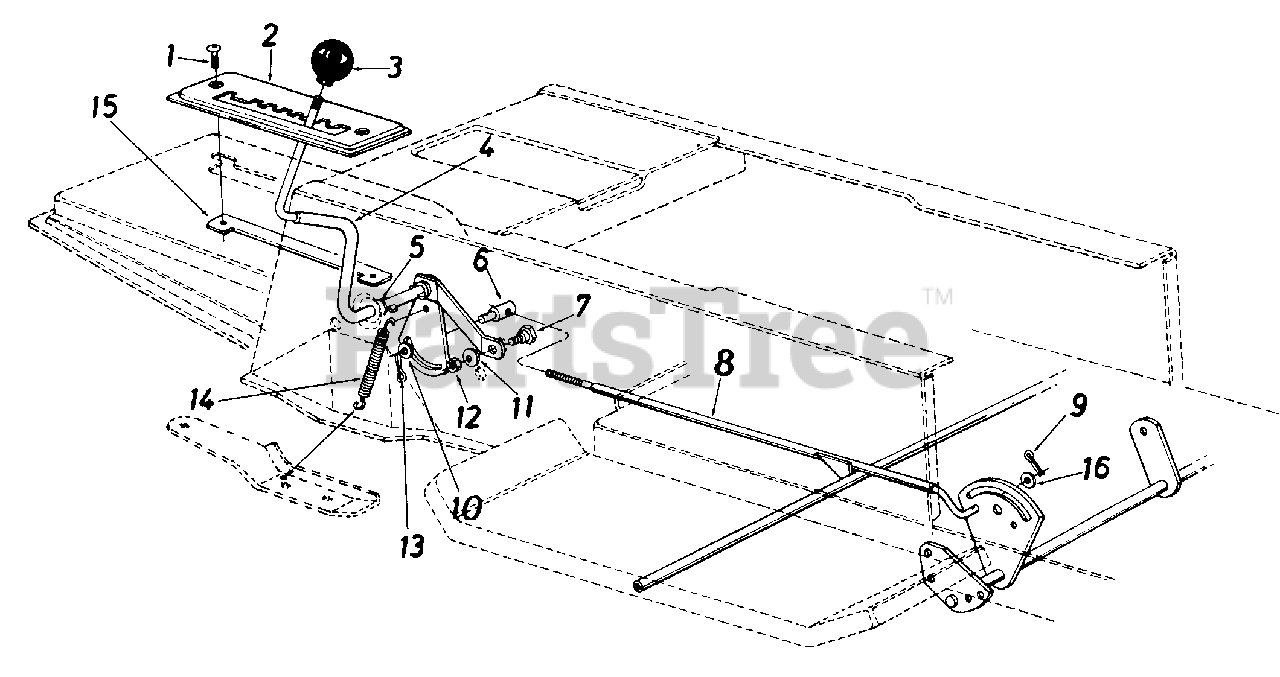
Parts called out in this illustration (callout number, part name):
1	Truss Mach. Scr. 1/4-20 x .75" Lg.
4	Speed Selector Cam Ass'y.
5	Flat Washer .53" I.D. x .93"
6	Ferrule 3/8-24 x .37" Dia.
7	Shoulder Bolt .435" Dia. x .1 60
8	Speed Control Rod Ass'y.
9	Cotter Pin 3/32" Dia. x .75"
10	Fl-Wash. .385" I.D. x .62" O.D.
11	L-Wash. 5/16" I.D.
12	Hex Nut 5/16-18 Thd.
13	Cotter Pin 3/32 Dia. x .75"
14	Spring
15	Clamping Plate
16	Fl-Wash. .47" I.D. x .88" O.D.
